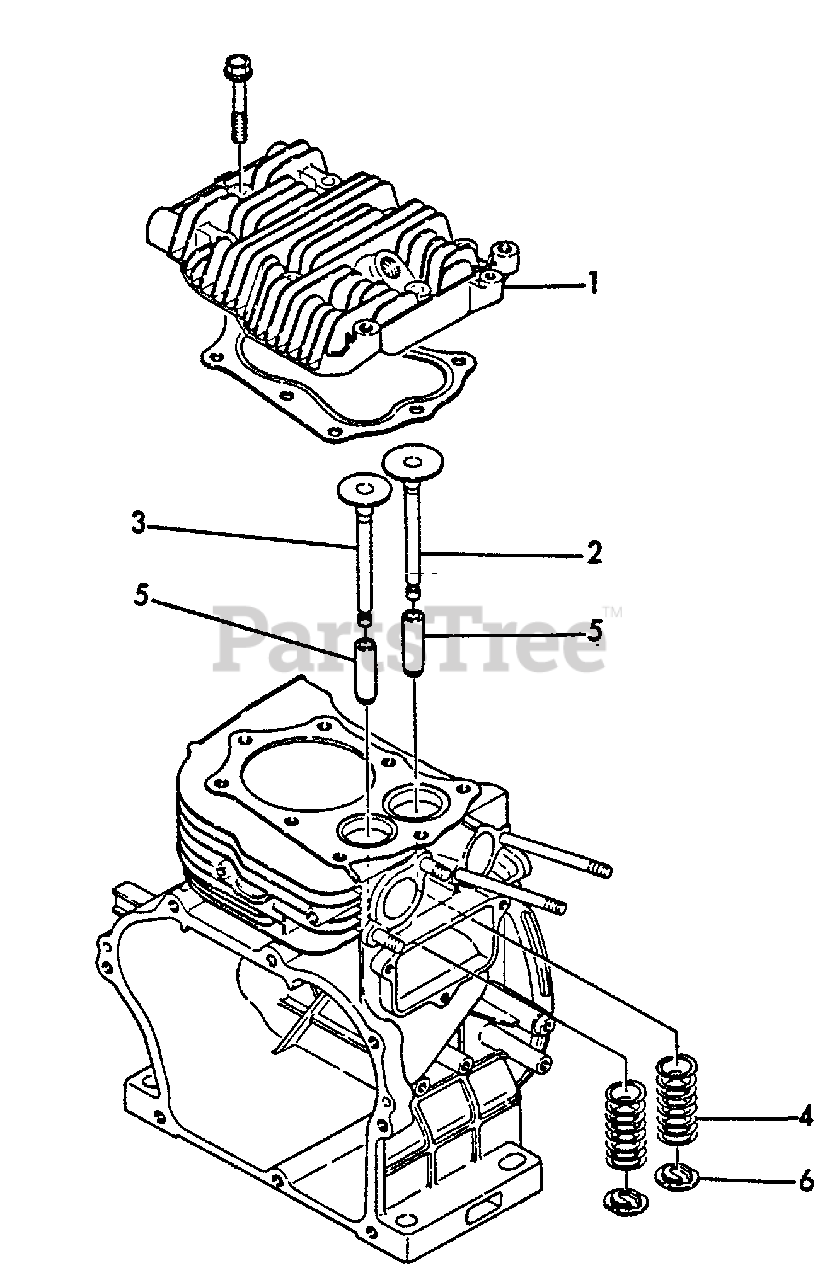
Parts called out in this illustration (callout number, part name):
1	HEAD, CYLINDER
2	VALVE, INTAKE
3	VALVE, EXHAUST
4	SPRING, VALVE
5	GUIDE, VALVE
